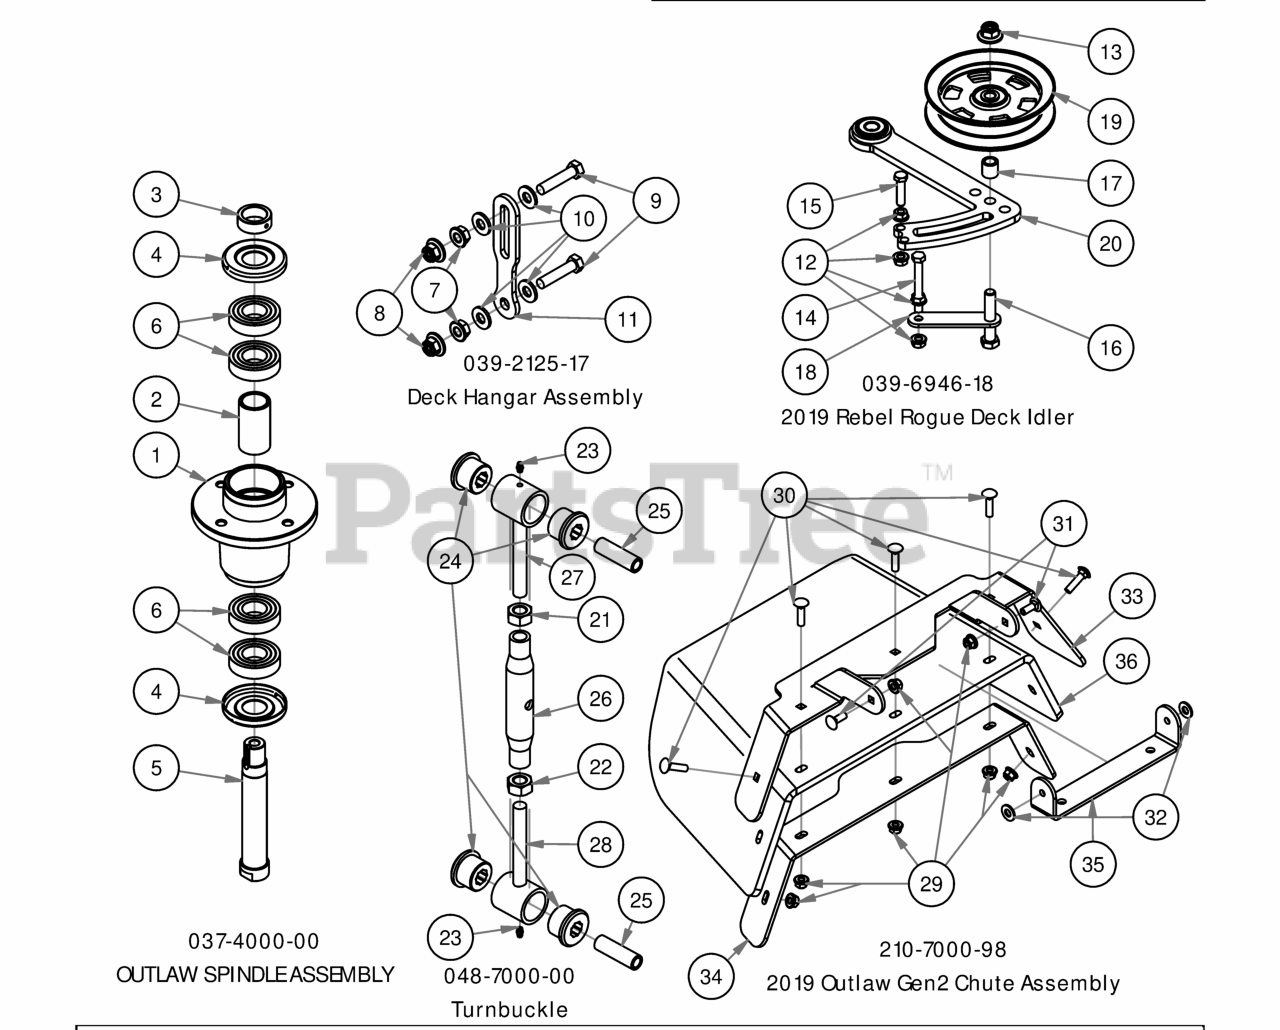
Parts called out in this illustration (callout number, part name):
1	4000 Series Spindle Housing
2	4000 Series Spindle Spacer
3	Locking Collar w/ 1/4"-20 Set Screw
4	Spindle Dust Cap
5	Spindle Shaft
6	Bearing - 6206
7	1/2" Flange Nut
8	1/2-13 Nylon Flange Nut
9	1/2-13X 2-1/4 GR Hex Bolts
10	.505 Nylon Spacer
11	Deck_Hanging_Tab
12	3/8" Flange Nut
13	1/2-13 Nylon Flange Nut
14	3/8-16x3 grade 5 hex bolt
15	3/8 x 1.5" Bolt
16	1/2" x 2 3/4" Hex Bolt
17	Spacer 3/4 OD x 1/2 ID x 3\4 Length
18	Belt Tensioner Retainer Plate
19	5" Idler Pully
20	2019 Deck Tensioner
21	Hex Nut, 11/16-12
22	Hex Nut, 11/16-12 Left Handed
23	1/4" Press in Grease Fitting
24	Polyeurethane Bushing
26	2015 Outlaw Toplink Body
27	Right-Handed End
28	2015 Outlaw Toplink LH End
29	5/16" Nylon Flange Nut
30	5/16" x 1 1/4" Carriage Bolt
31	5/16" x 7/8" Carriage Bolt
32	.360 ID Plastic Washer
33	2019 Upper Chute Bracket
34	2019 Lower Chute Bracket
35	2019 Chute Hanger
36	2019 Belted Chute with Logo
